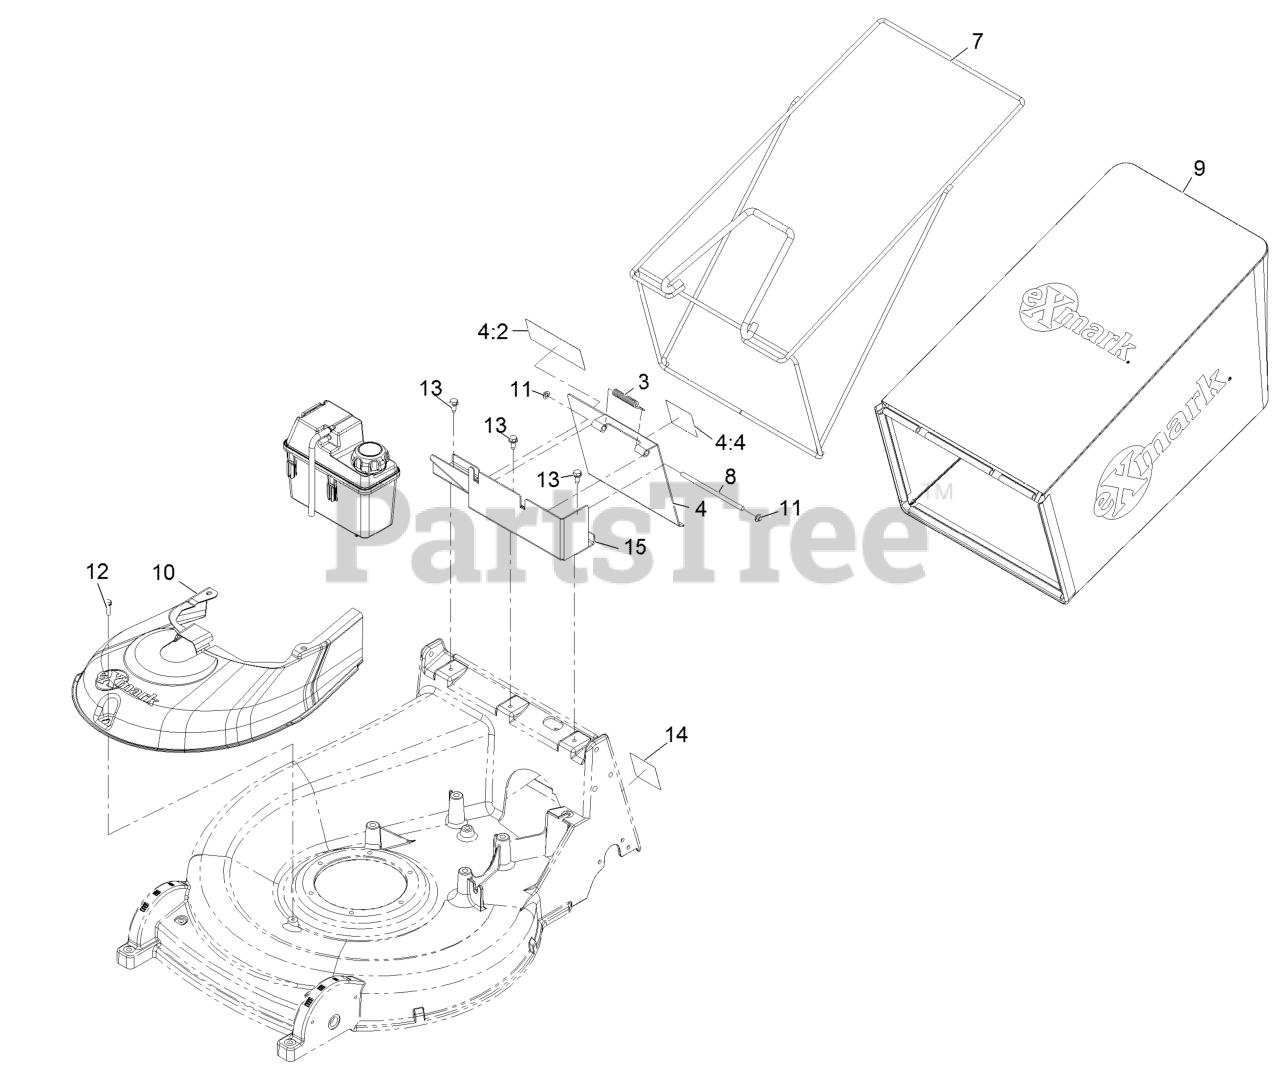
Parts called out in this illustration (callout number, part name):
3	SPRING-TORSION
4	ASM,DOOR W/DECALS METRO 2
4:2	DECAL-WARNING
4:4	DECAL-WARNING, BLOCK
7	FRAME-BAG
8	ROD-PIVOT, DOOR
9	BAG,METRO 26 3.0 BU
10	COVER,SPINDLE
11	NUT-PUSH
12	SCREW-HWHTF
13	Screw-HWH 5/16-18 X 3/4 Tf
14	DECAL,SERVICE M26
15	BRACKET,DOOR/TANK MOUNT
